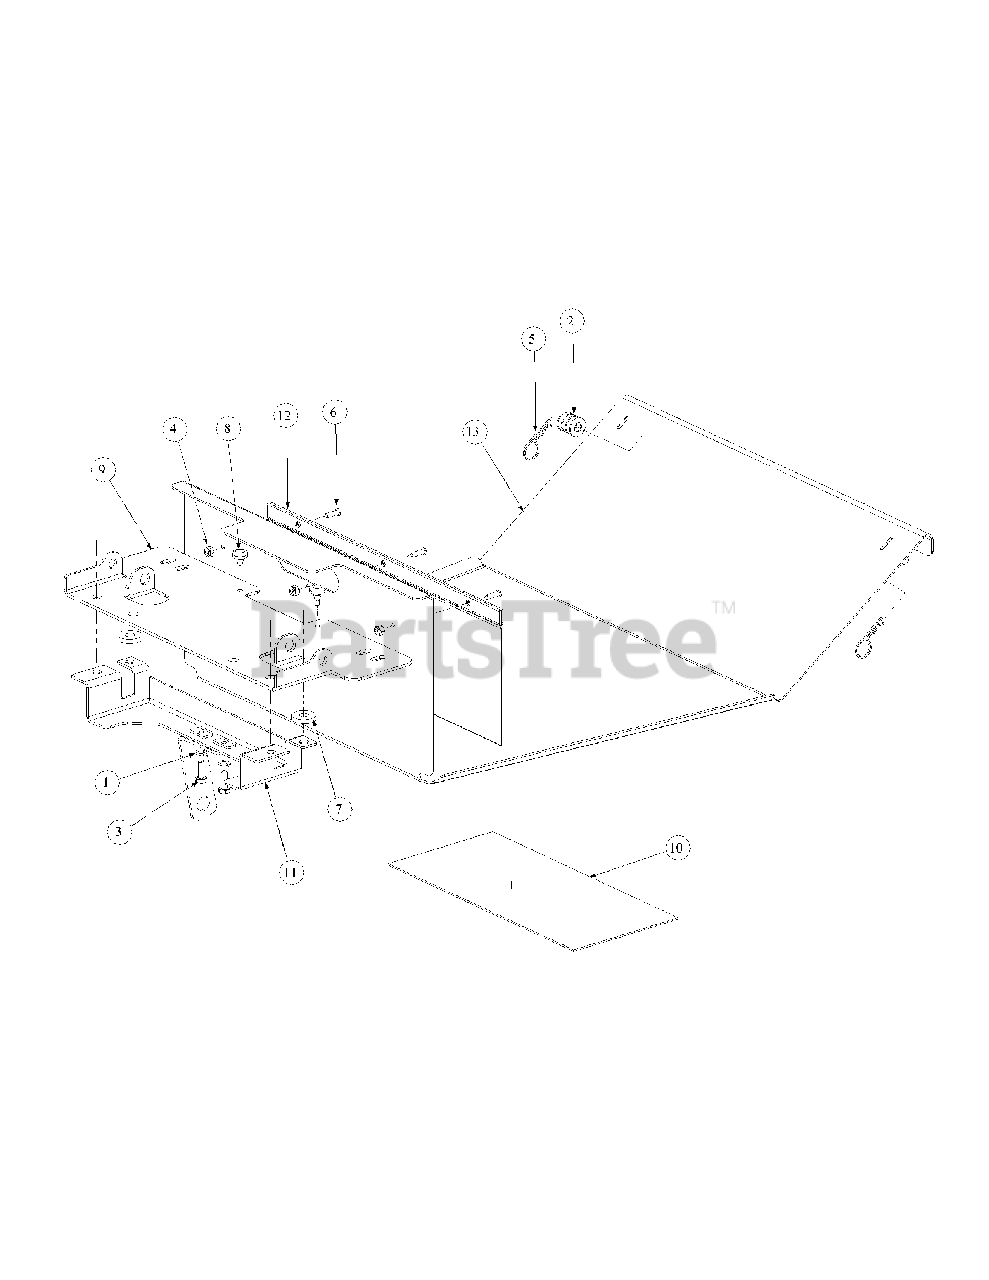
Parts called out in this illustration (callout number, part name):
1	Lock Washer, 1/4
3	Hex Cap Screw, 1/4-20, .75
4	Lock Nut, Nylon Insert, 10-32
5	Hair Pin, 3/8-1/2
6	Screw, Phillips Head, Machine, 10-32 x 5/8
7	Washer
8	Rubber Bumper, .62 OD x .22 Thick
10	Label, Belt Routing and Lubrication
11	Support, Seat Bracket
12	Bag, Debris Storage
13	Floor Panel Assembly
